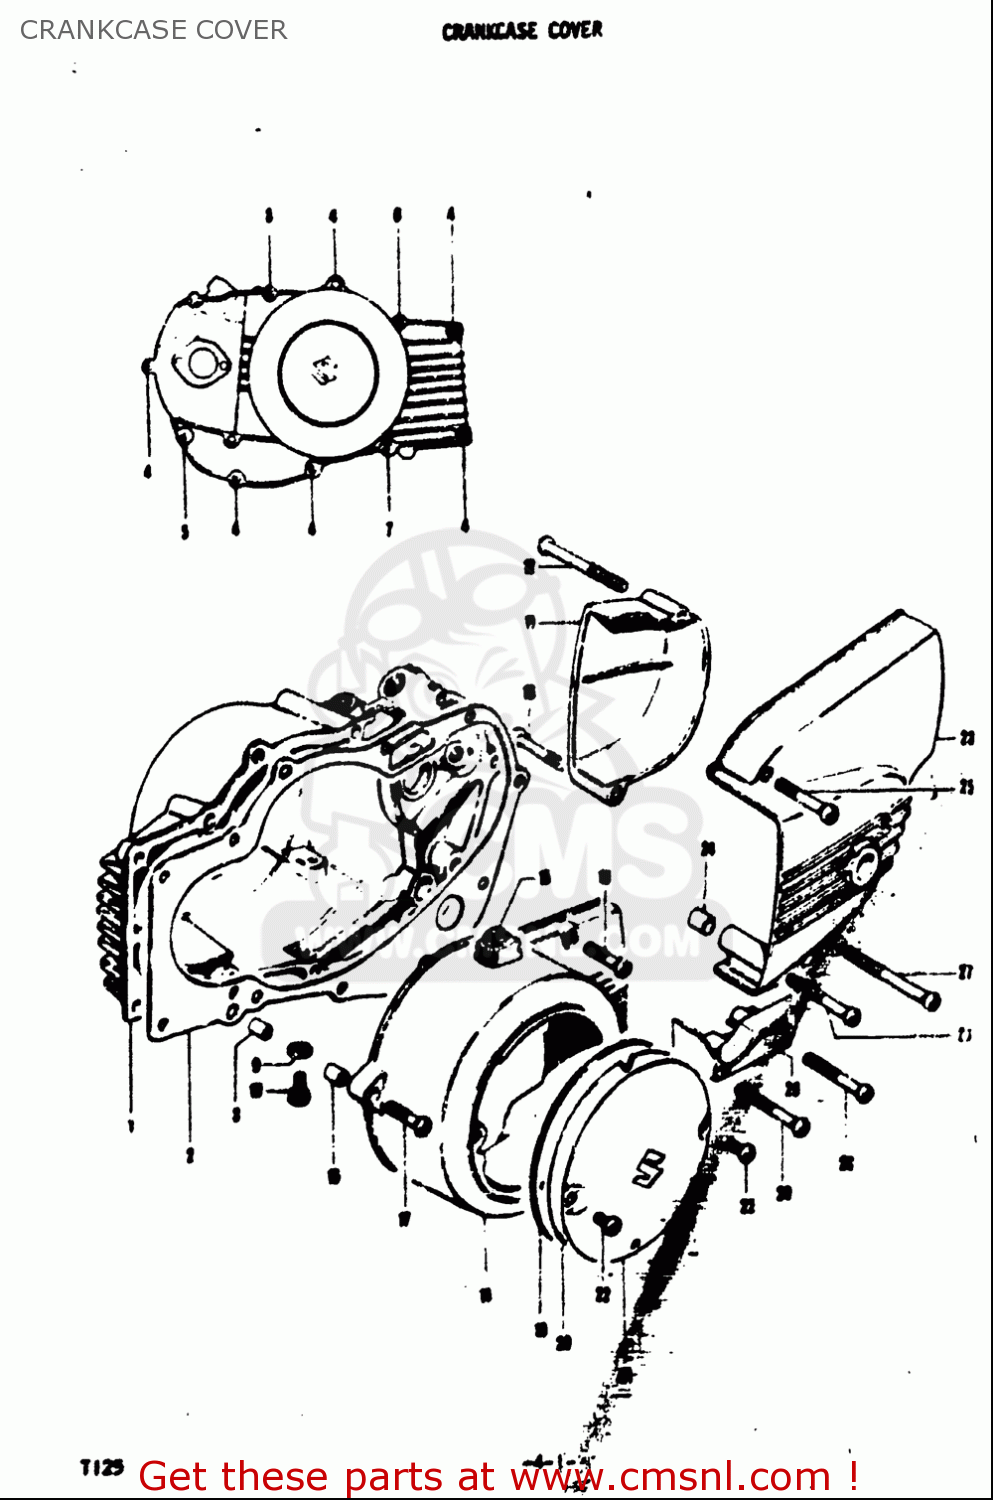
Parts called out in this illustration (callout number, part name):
2	GASKET,CLUTCH COVER (MCA)
3	PIN
4	SCREW
5	SCREW
6	SCREW
7	SCREW
8	SCREW
9	GASKET(6.2X11X1) (NAS)
12	SCREW
16	PIN
19	GASKET,OIL PAN
20	GASKET
24	PIN
